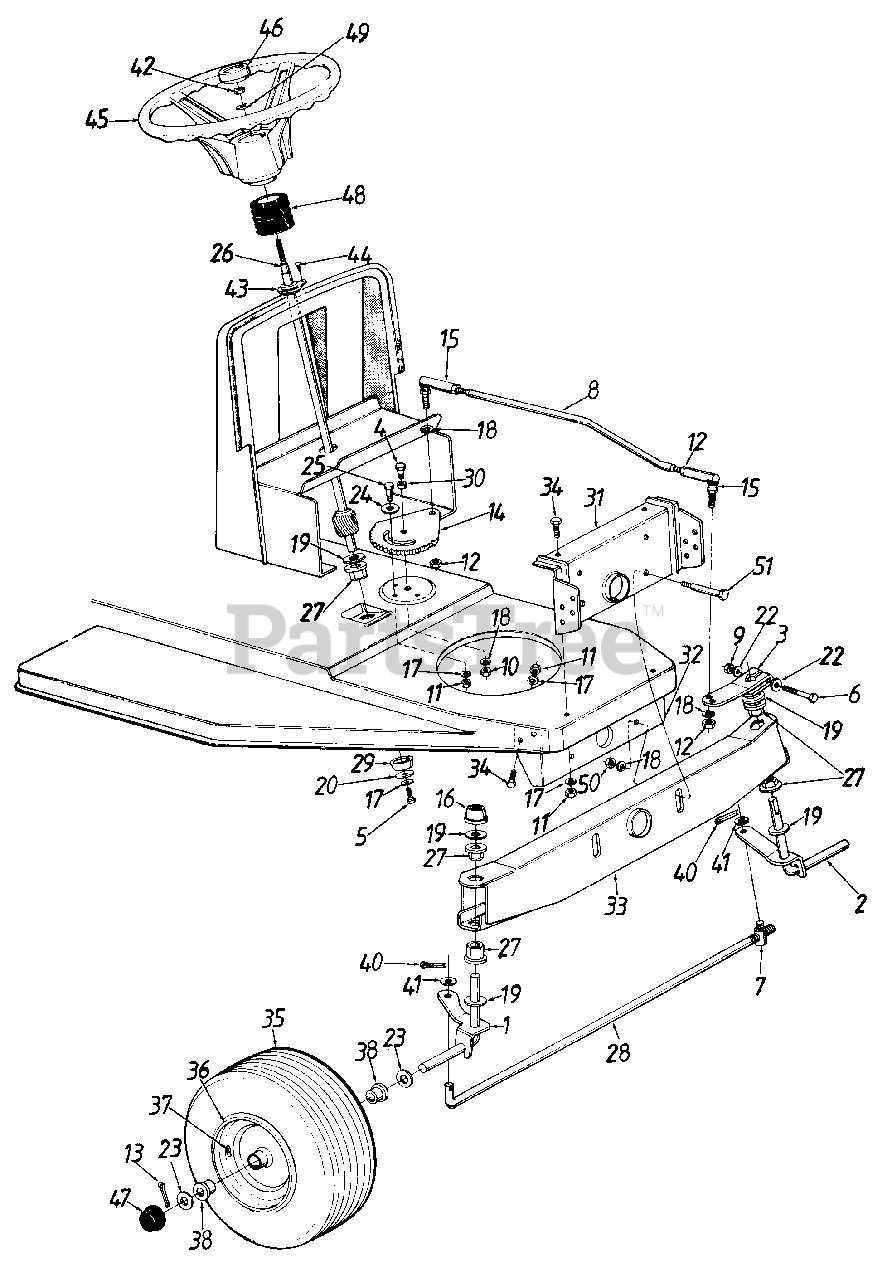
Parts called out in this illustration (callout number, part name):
1	Front Axle Ass'y.-R . H .
2	Front Axle Ass'y.-L. H .
3	Steering Arm
4	Hex Bolt 3/8-24 x 1" Lg.
5	Hex Bolt 5/16-18 x .62
6	Hex Bolt 5/16-24 x 2" Lg.
7	Ferrule
8	Steering Drag Link
9	Hex L-Nut 5/16-24 Thd.
10	Hex Nut 3/8-24 Thd.
11	Hex Nut 5/16-18 Thd.
12	Hex Jam Nut, 3/8-24
13	Cotter Pin 1/8 Dia.
14	Steering Gear Segment
15	Drag Link Ball Joint 3/8-24 Thd.
16	Push Cap
17	L-Wash. 5/16" I.D.
18	L-Wash. 3/8" I.D.
19	Fl-Wash. .64" I.D. x 1.24"
20	Fl-Wash. .344" I.D. x 1.125"
22	Spr. Wash. .32 I.D. x .62
23	Fl-Wash. .635 I.D. x 1.585
24	Fl-Wash. .44 I.D. x 1.38
25	Shld. Bolt .437 Dia. x .350
26	Steering Shaft
27	Hex Flange Brg. .634 Dia.
28	Tie Rod 18.37 Lg.
29	Spacer .985 I.D.
30	Spacer .380 I.D.
31	Front Pivot Bar Support Brkt.
32	Rear Pivot Bar Support Brkt.
33	Pivot Bar Ass'y.
34	Hex Bolt 5/16-18 x .75" Lg.
35	Front Wheel Ass'y. Comp. 13 x 6
37	Air Valve
38	Flange Bearing .632 I.D.
40	Cotter Pin 3/32" Dia.
41	Fl-Wash. .406" I.D. x .75"
42	Hex Nut 5/16-24 Thd.
43	Steering Column Brg.
44	Cr-Sunk Scr. #10 x 5/8" Lg.
45	Steering Wheel
46	Steering Wheel Cap
47	Hub Cap
48	Bellow Steering Column
49	Bell-Wash. .345 I.D. x .88
50	Hex Nut 3/8-16 Thd.
51	Shld. Bolt 1/2" Dia. x 2.32"
